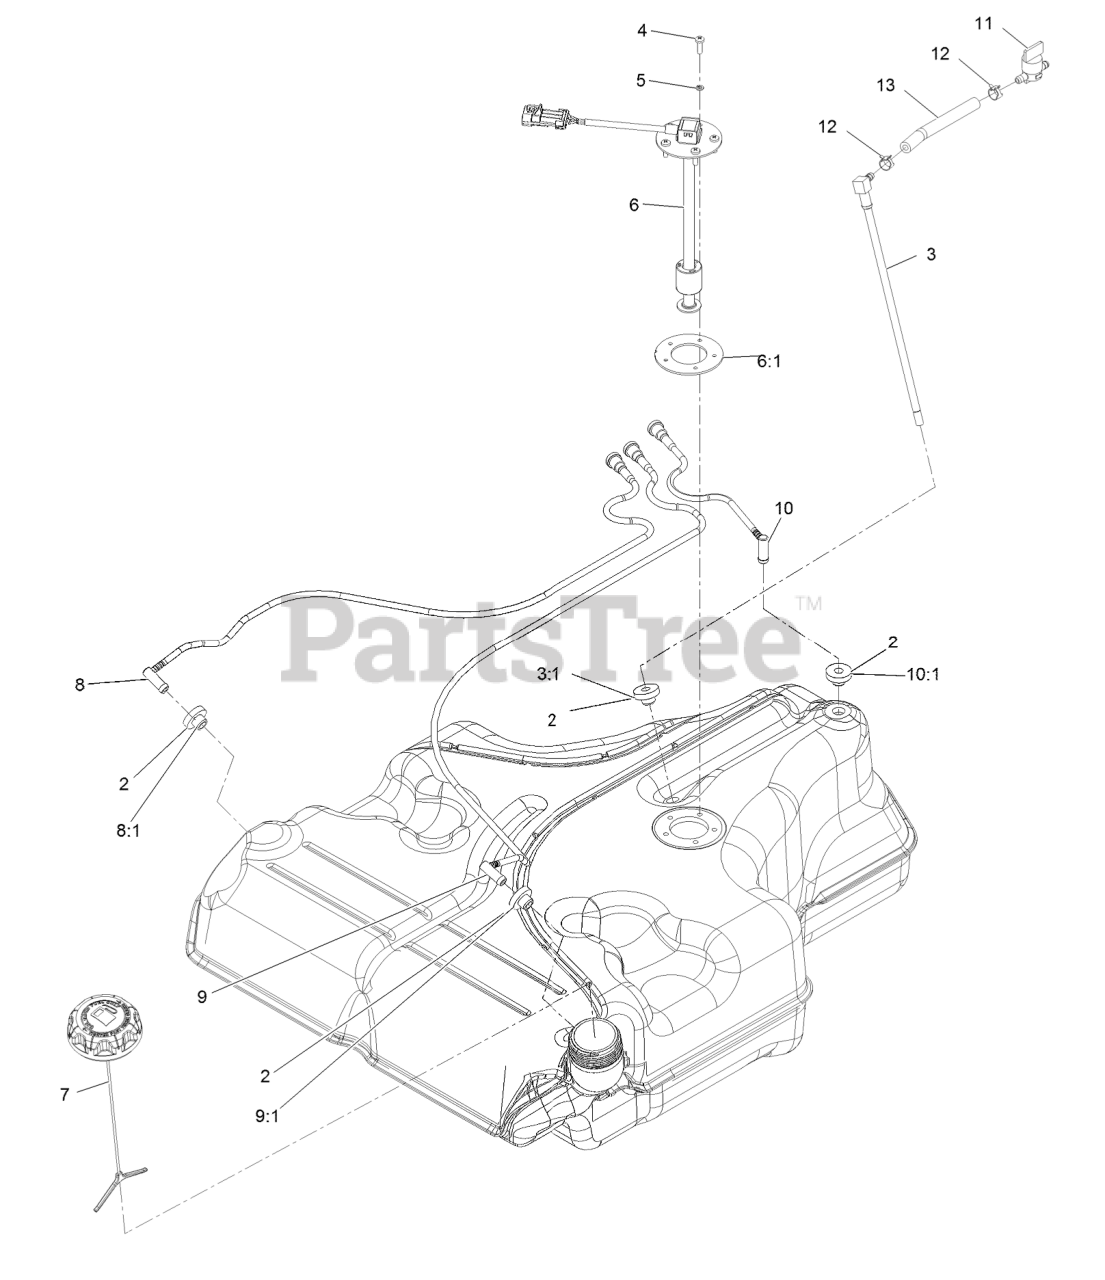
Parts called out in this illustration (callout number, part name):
2	BUSHING
3	FUEL LINE KIT (WITH GROMMET)
3:1	BUSHING
4	SCREW-PPH
5	WASHER-LOCK
6	FLOAT-SENDER, FUEL
6:1	Gasket-Sender
7	CAP-FUEL, RATCHETING
8	RH VENT LINE KIT (WITH GROMMET)
9	LH VENT LINE KIT (WITH GROMMET)
10	REAR VENT LINE KIT (WITH GROMMET)
11	VALVE-FUEL
12	CLAMP-HOSE
13	HOSE-FUEL
